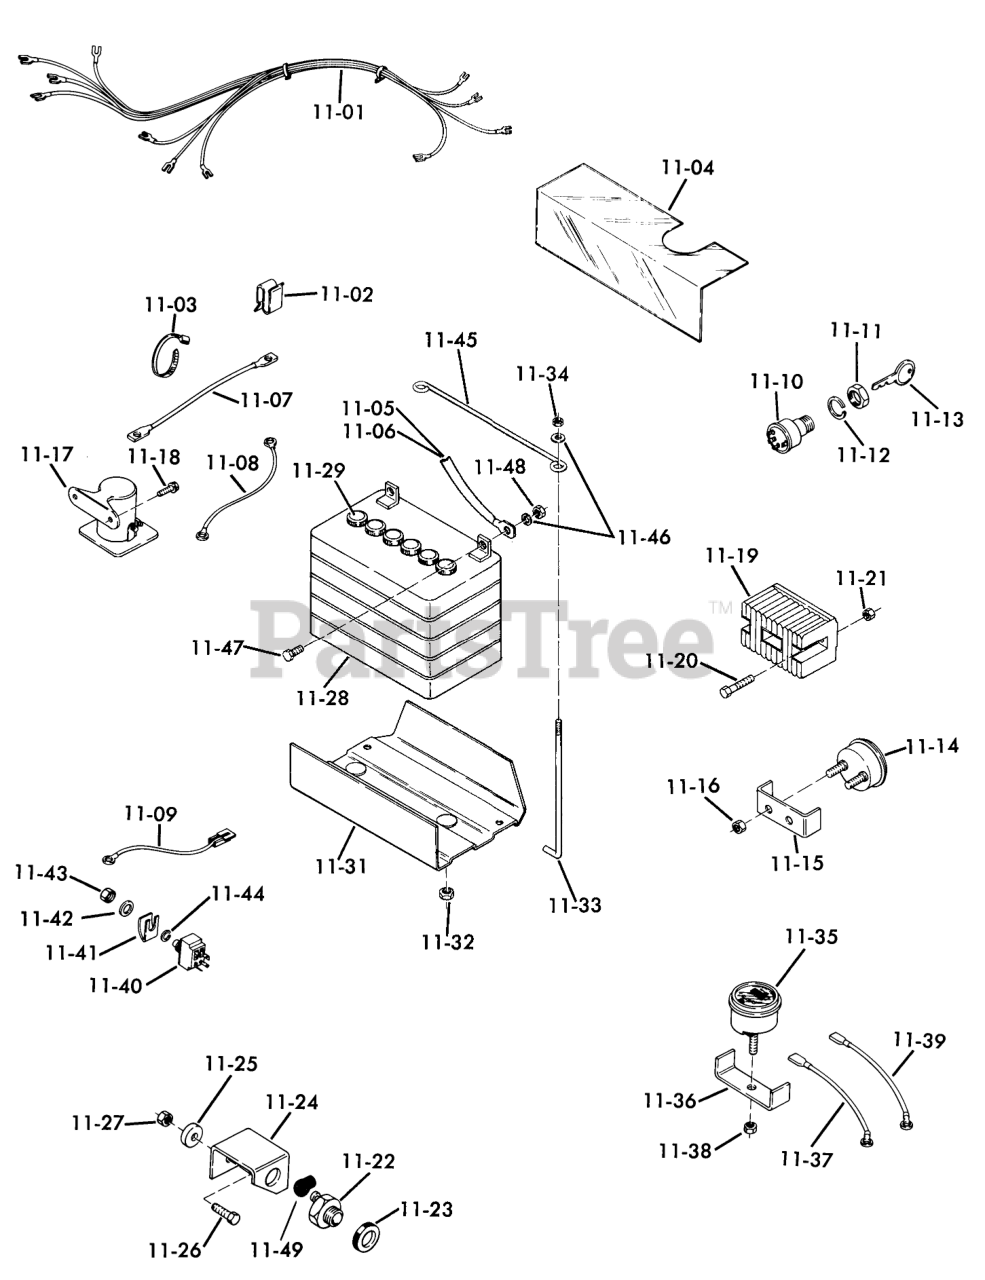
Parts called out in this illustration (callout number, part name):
11-01	WIRING HARNESS & DIA
11-02	SPEED CLIP
11-03	PLASTIC TIE
11-04	CONTROL PROTECTOR
11-05	Wire
11-06	Wire
11-07	Wire
11-08	WIRE ASSY
11-09	Wire Assy.
11-10	SWITCH-IGNITION
11-12	LOCKWASHER
11-13	Key-EL
11-14	AMMETER W/CLAMP
11-15	Clamp
11-16	HEX NUT 10-32 E.S.
11-17	Solenoid
11-18	Screw
11-19	REGULATOR-RECTIFIER
11-20	Bolt
11-21	Nut
11-22	SWITCH SAFETY
11-23	NUT-SPECIAL 9/16-18
11-24	Bracket
11-25	WASHER
11-26	BOLT
11-27	Nut
11-28	Battery
11-31	Battery
11-32	Nut
11-33	Hook
11-34	Nut
11-35	Hour Meter
11-36	Clamp
11-37	SY WIRE HR METER G
11-38	Nut
11-39	Wire Assy
11-40	SWITCH-CLUTCH
11-41	CLIP-SWITCH
11-42	WASHER
11-43	NUT-HEX
11-44	TAB-WASHER
11-45	ROD-HOLD DOWN
11-47	Bolt
11-48	Nut
11-49	Terminal Cover
